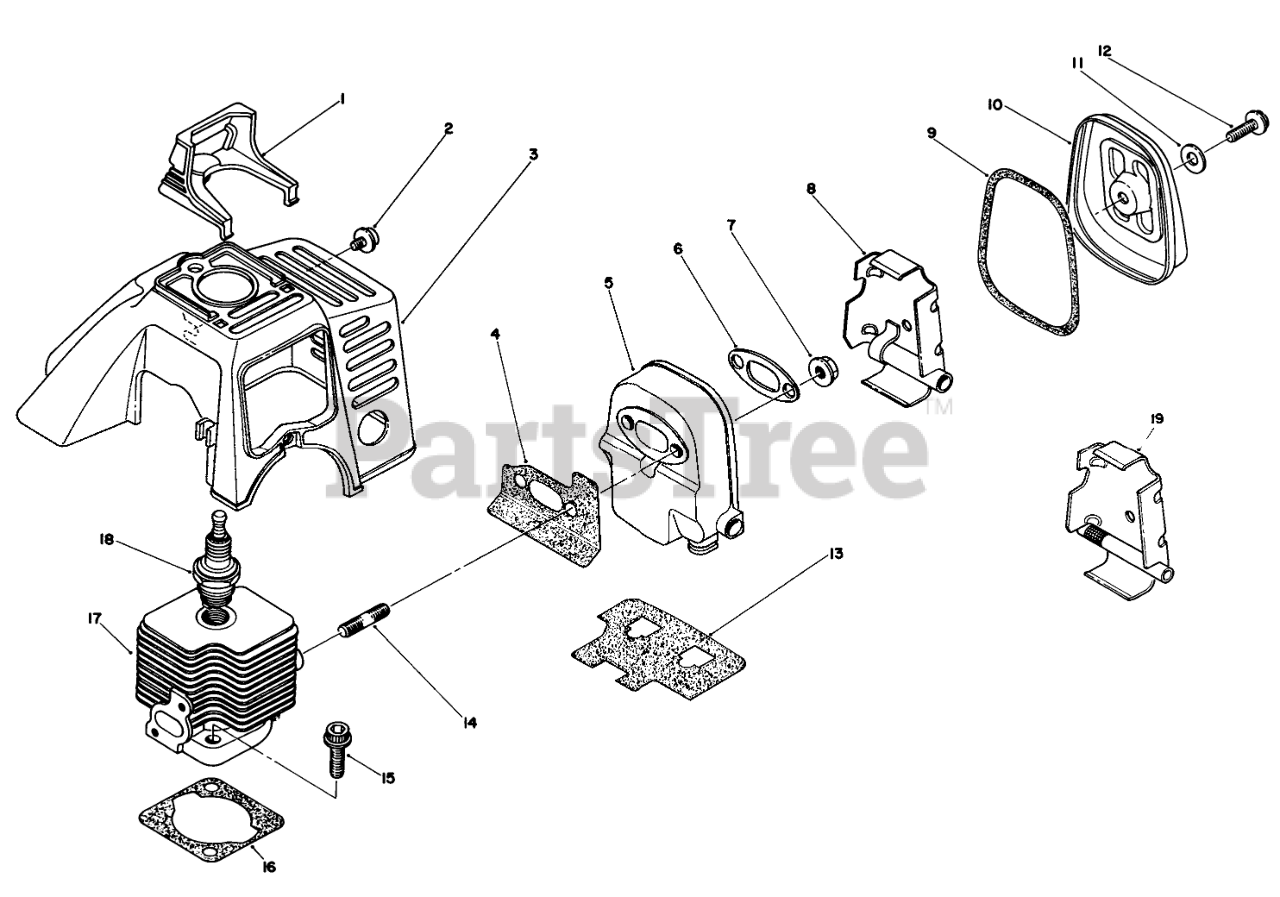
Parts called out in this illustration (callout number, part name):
1	SPARK PLUG GUARD
2	SCREW & WASHERE
3	COVER-TOP
4	Gasket-Muffler
5	Body-Muffler
6	PLATE
8	Plate
9	GASKET
10	MUFFLER LID
11	Washer-Seal
12	Bolt-Flange
13	Gasket
15	FLANGE BOLT
16	CYL GASKET
17	Cylinder
18	SPARK PLUG (NGK)
19	Spark Arrester Muffler (Optional)
